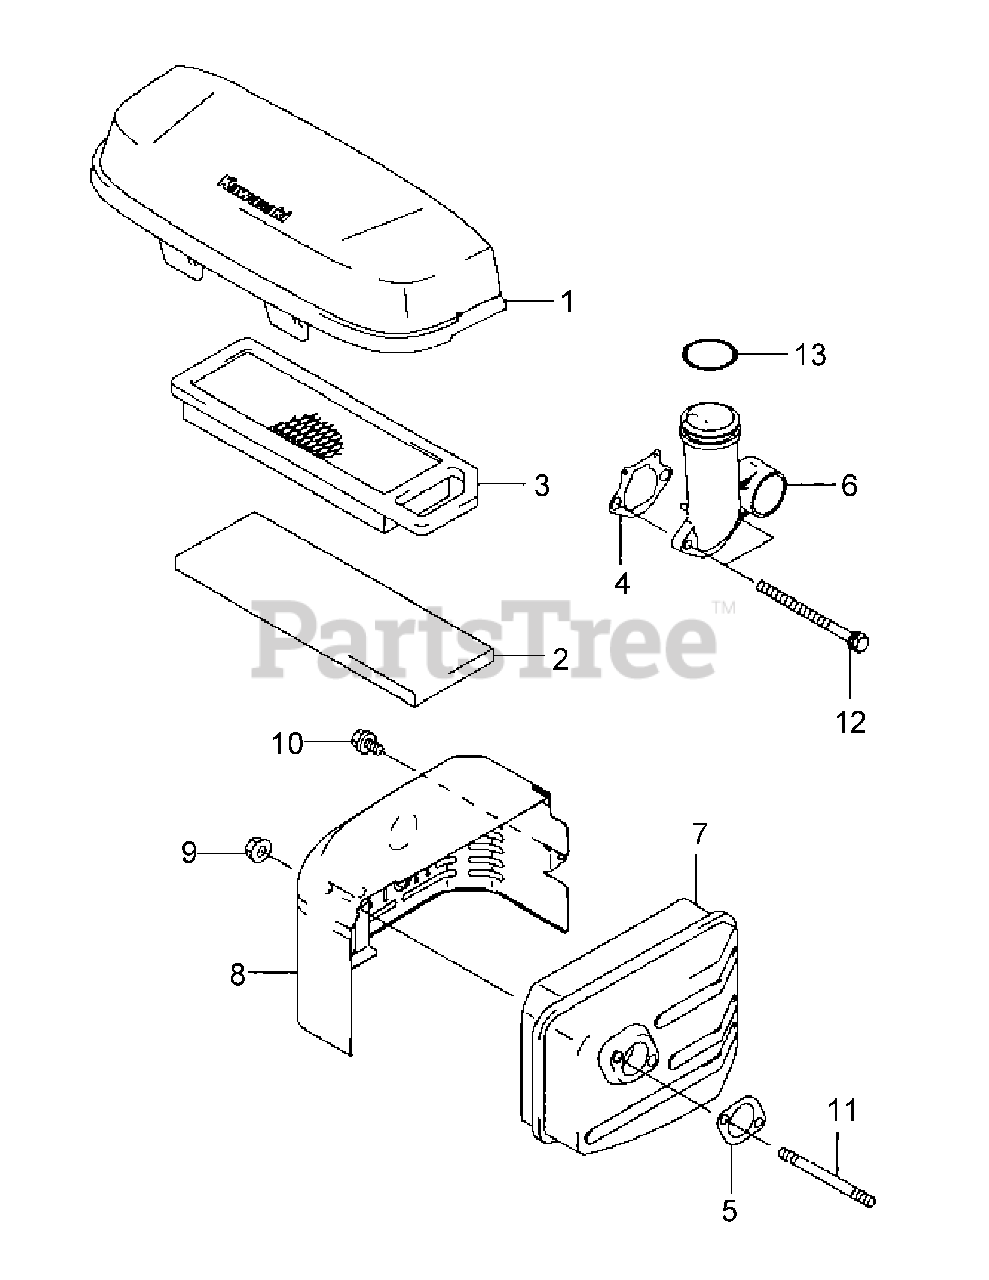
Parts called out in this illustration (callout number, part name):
1	Air Filter Case
2	Pre Filter Element
3	Air Filter Element
4	Intake Pipe Gasket
5	Muffler Gasket
7	Muffler
8	Muffler Cover
9	Nut
11	Stud Bolt
